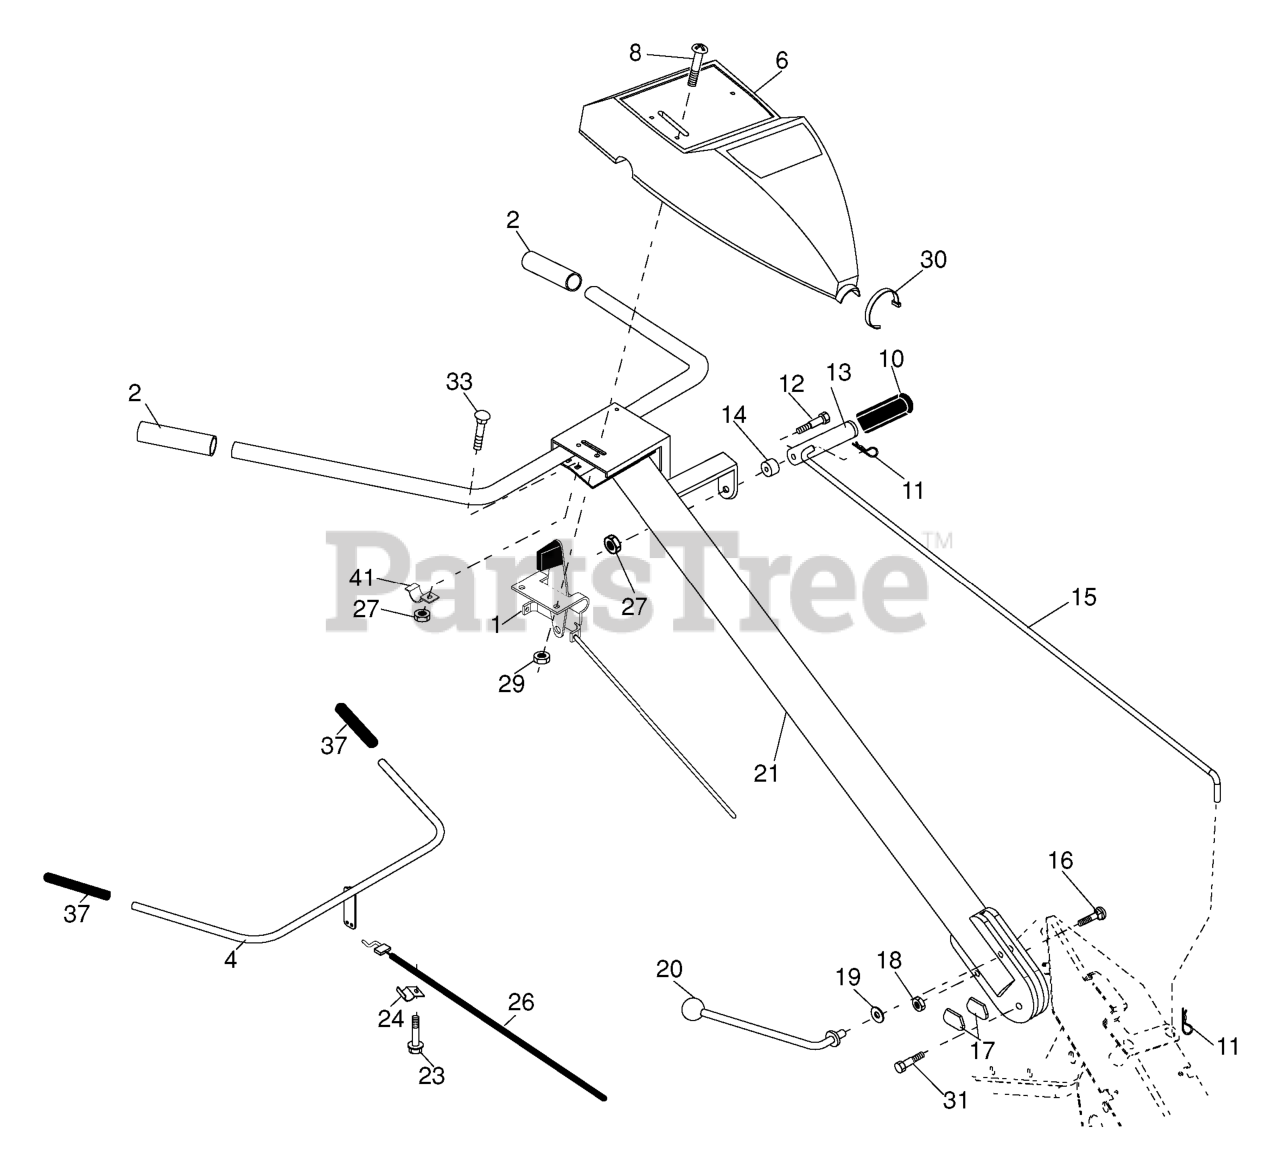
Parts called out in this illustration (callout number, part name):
1	THROTTLE.CONTROL.RT.INTEK.50
2	KIT.GRIP.HANDLE.5.00.BLK.VINYL
4	CONTROL BAR ASSY
6	RP CONTROL PANEL
8	SCREW.PNHD.10-24
10	GRIP T
11	RETAINER M
12	SHOULDER BOLT ST
13	HANDLE.SHIFT.TILLER
14	GROMMET.RUBBER.CRT.TILLER
15	SHIFT ROD CRT
16	BOLT D
17	LOCK.HANDLE.CRT
19	WASHER CRT
20	LEVER.LOCK.CRT
21	REPL BY 532 1805-17
23	TAPPING SCREW
24	CONDUIT.CLIP.PLATED
26	CABLE.CLUTCH
27	NUT T
29	NUT **
30	TIE CABLE CRT
31	BOLT.PIVOT
33	BOLT
37	GRIP BAR CRT(1)
41	CLAMP.BAR.CRT.BLACK
